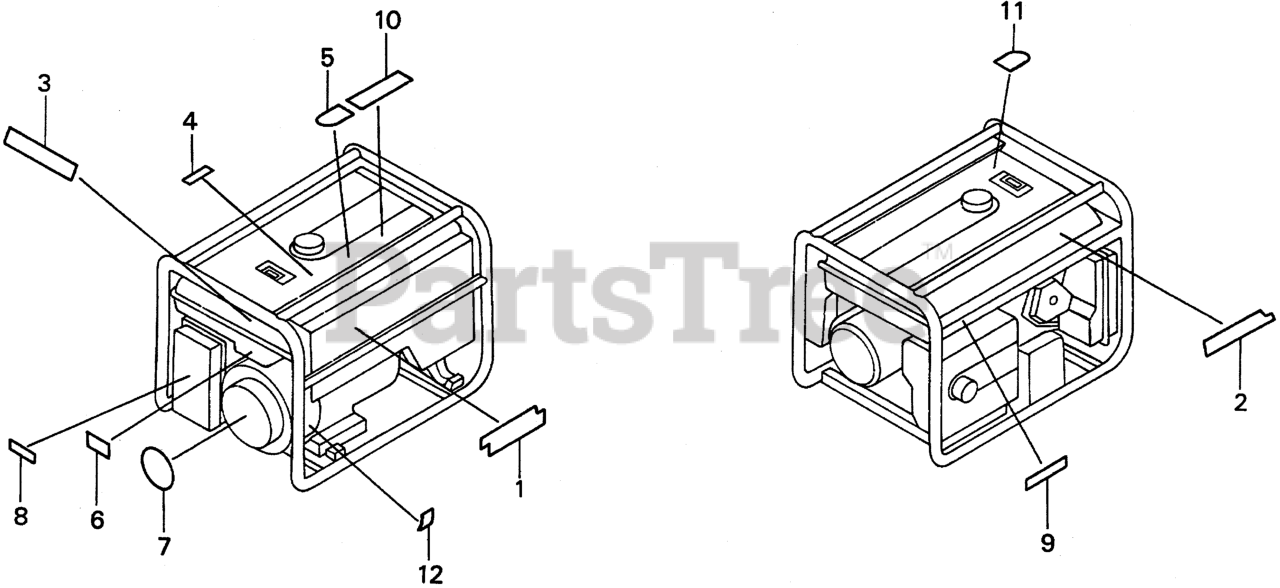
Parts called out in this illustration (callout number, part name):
2	MARK, HONDA (NOT AVAILABLE)
3	PLATE, CAUTION
4	LABEL, RAIN WARNING (ENGLISH)
5	MARK, CAUTION (ENGLISH/FRENCH)(SPANISH)
6	MARK, CHOKE
7	MARK, OIL ALERT (NOT AVAILABLE)
8	MARK, AIR CLEANER (ENGLISH)
9	MARK, EX. CAUTION (ENGLISH/FRENCH)
10	MARK, CAUTION (CO)(ENGLISH/FRENCH)(SPANISH)
11	LABEL, CONNECT WARNING (ENGLISH)
12	MARK, OIL CAUTION
